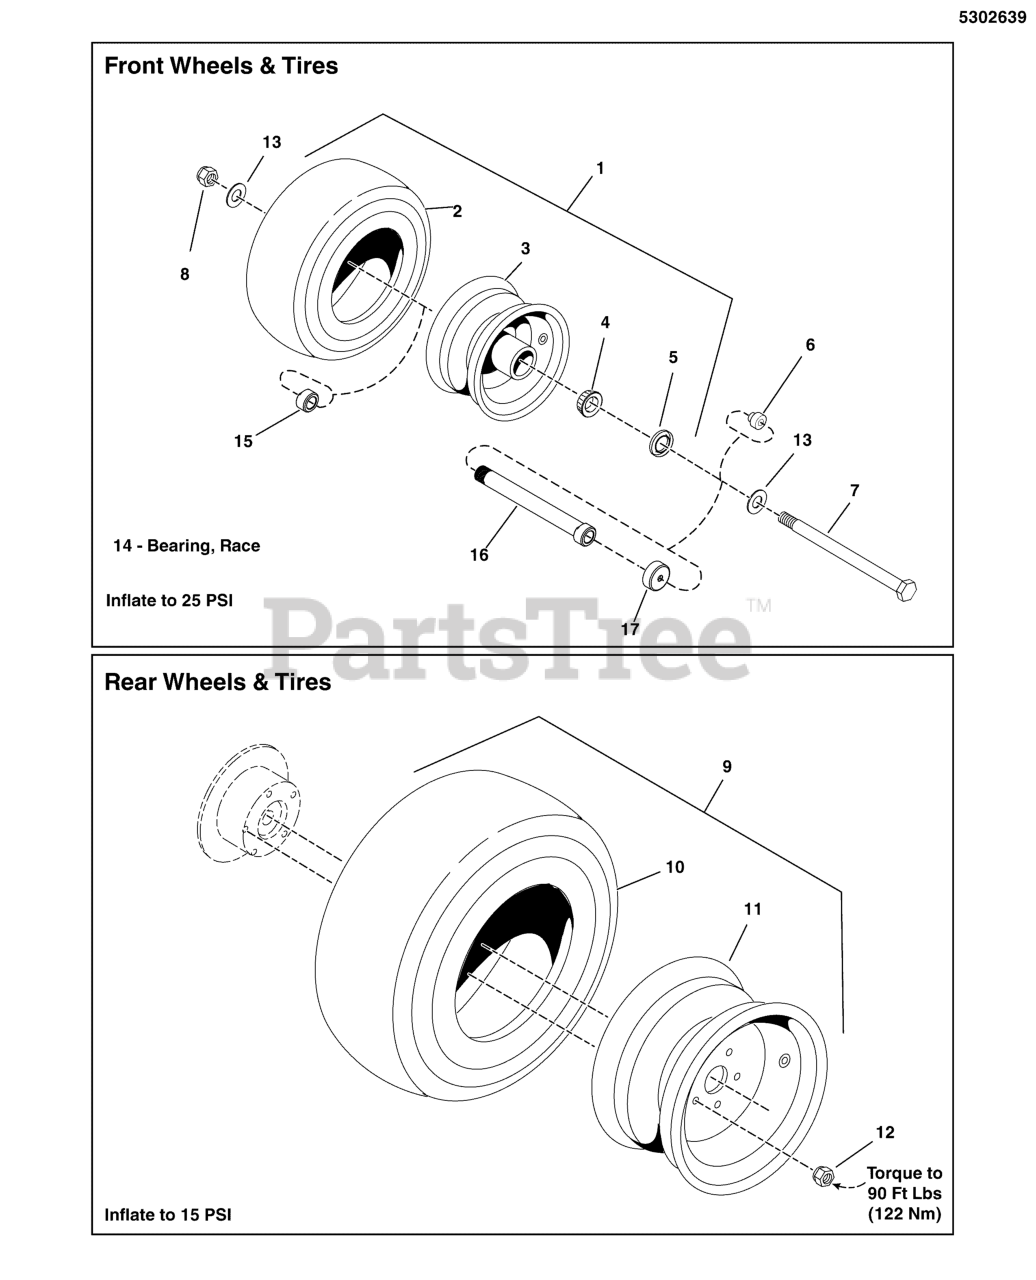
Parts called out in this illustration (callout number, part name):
1	TIRE ASSM, 13 X 6.5 - 6, PNE / TB
2	TIRE, RUBBER ONLY
3	WHEEL ASSEMBLY
4	BEARING, Tapered Roller
5	SEAL, GREASE
6	ADAPTER, CASTER AXLE, CZ
7	BOLT, 1/2-13 X 9 GD5 YZ
8	NUT, Hex Flange, Nylock, 1/2-13
9	TIRE WHEEL ASM, 24X12.00-12, TURF MASTER
9	TIRE/WHEEL ASM, 24X12.00-12, TURF SMART
10	TIRE, 24 X 12 X 12
10	TIRE, 24X12.00-12, TURF SMART
11	WHEEL, 12 X 8.5
12	NUT, 1/2-20, FOR WHEEL BOLT SILVER
13	WASHER, 1/2 SAE
14	BEARING, RACE
15	NUT, BEARING ADJUSTER, AXLE
16	BEARING ADJUSTER, SPACER, 7.062 LG
17	DEBRIS COVER, CASTER WHEELS
